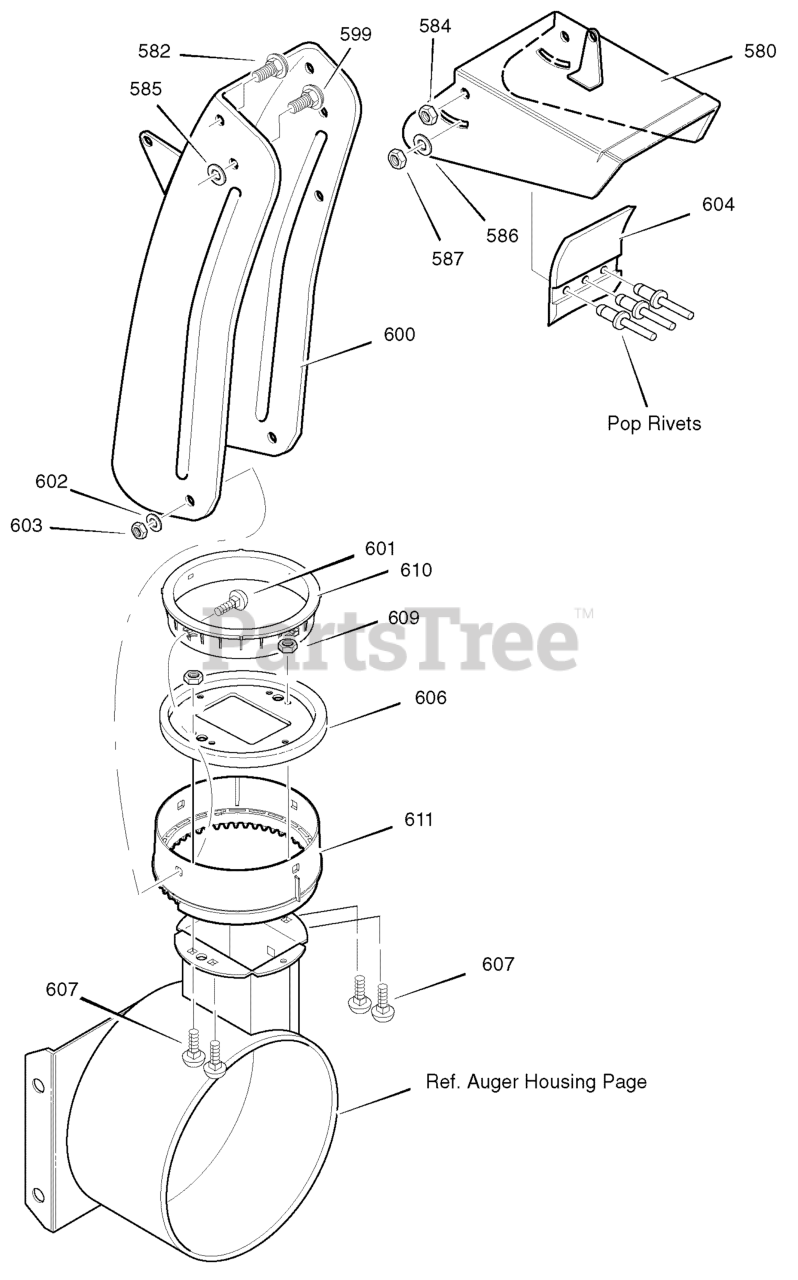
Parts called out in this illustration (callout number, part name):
580	CHUTE, UPPER W/REMOTE
582	SCREW, 5/16-18 x 0.75
584	NUT
585	WASHER, PLASTIC
586	WASHER, PLASTIC
587	NUT
599	SCREW, 5/16-18 x 1.50
600	CHUTE, LOWER W/REMOTE
601	BOLT
602	WASHER, FLAT
603	NUT
606	CHUTE COLLAR
610	RETAINER, RING INNER
611	RETAINER, RING OUTER
